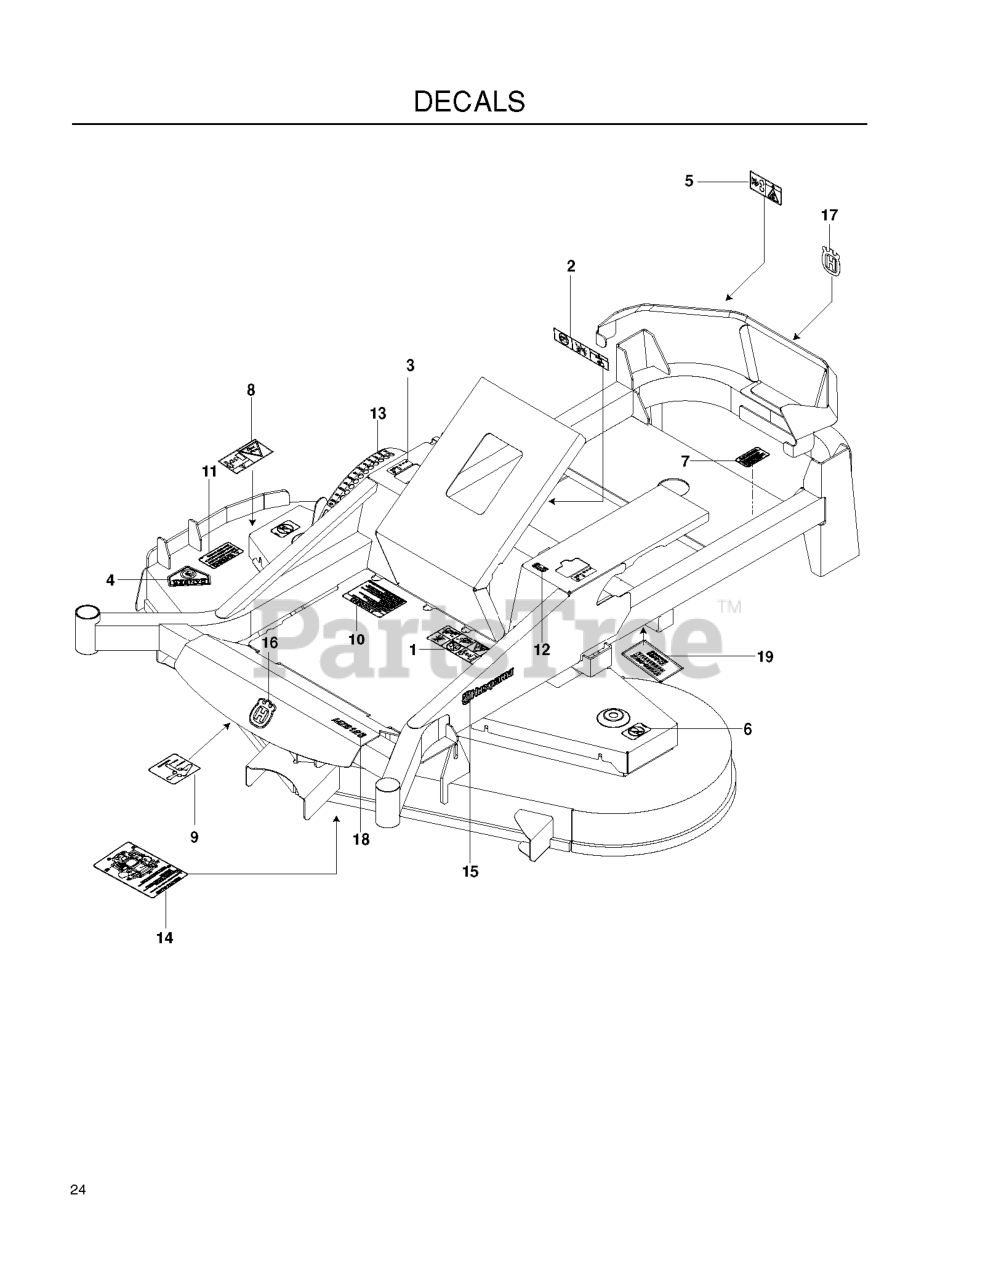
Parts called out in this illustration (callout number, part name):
1	DECAL, WARNING
2	EURO DECAL-BATTERY WARNIN6
3	DECAL, MOTION CONTROL
4	DECAL, CPSC
5	DECAL, BELT DRIVE
6	DECAL, NO STEP
7	DECAL, PROP. 65
8	DECAL, EURO SEVERING
9	RP DECAL, BELT ROUTING
10	DECAL, WARNING
11	DECAL, CAUTION
12	DECAL, F.S.T.
13	DECAL, HEIGHT ADJUST
14	DECAL, SERVICE
15	DECAL.HOOD.LOGO.ORANGE.HUSQVAR
16	DECAL, CROWN H 70MM
17	DECAL, CROWN H, 70MM
18	DECAL, MZ6128
19	HG_DECAL, ZT-3400
